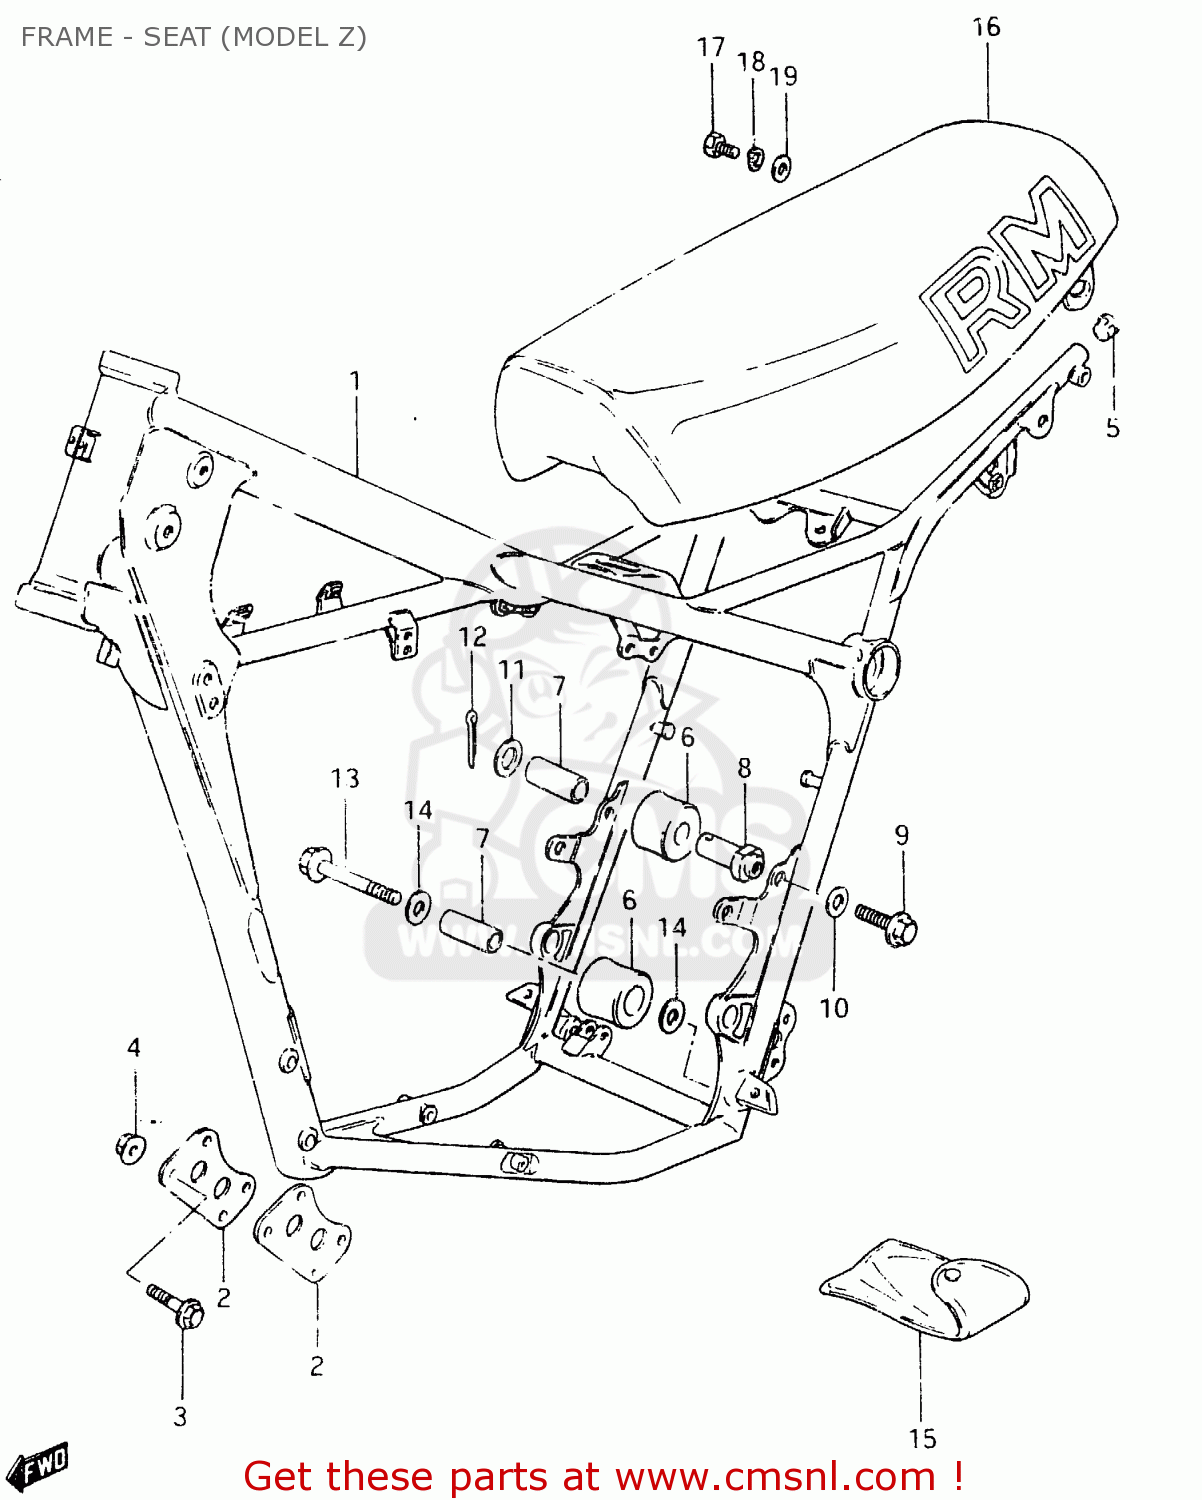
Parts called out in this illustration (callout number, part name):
1	FRAME
2	PLATE,ENGINE MOUNTING
3	BOLT(8X75)
4	NUT
5	PLUG(OD:17)
6	ROLLER,CHAIN LENGTH CONTROL
7	SPACER,CHAIN LENGTH ROLLER
8	BOSS,CHAIN LENGTH ROLL
9	BOLT
10	WASHER
11	WASHER
12	PIN 25X20
13	BOLT(8X45)
14	WASHER
15	TOOL SET
16	SEAT ASSEMBLY
17	BOLT
18	WASHER,LOCK,8.
19	WASHER (8.5X20X2.6)
